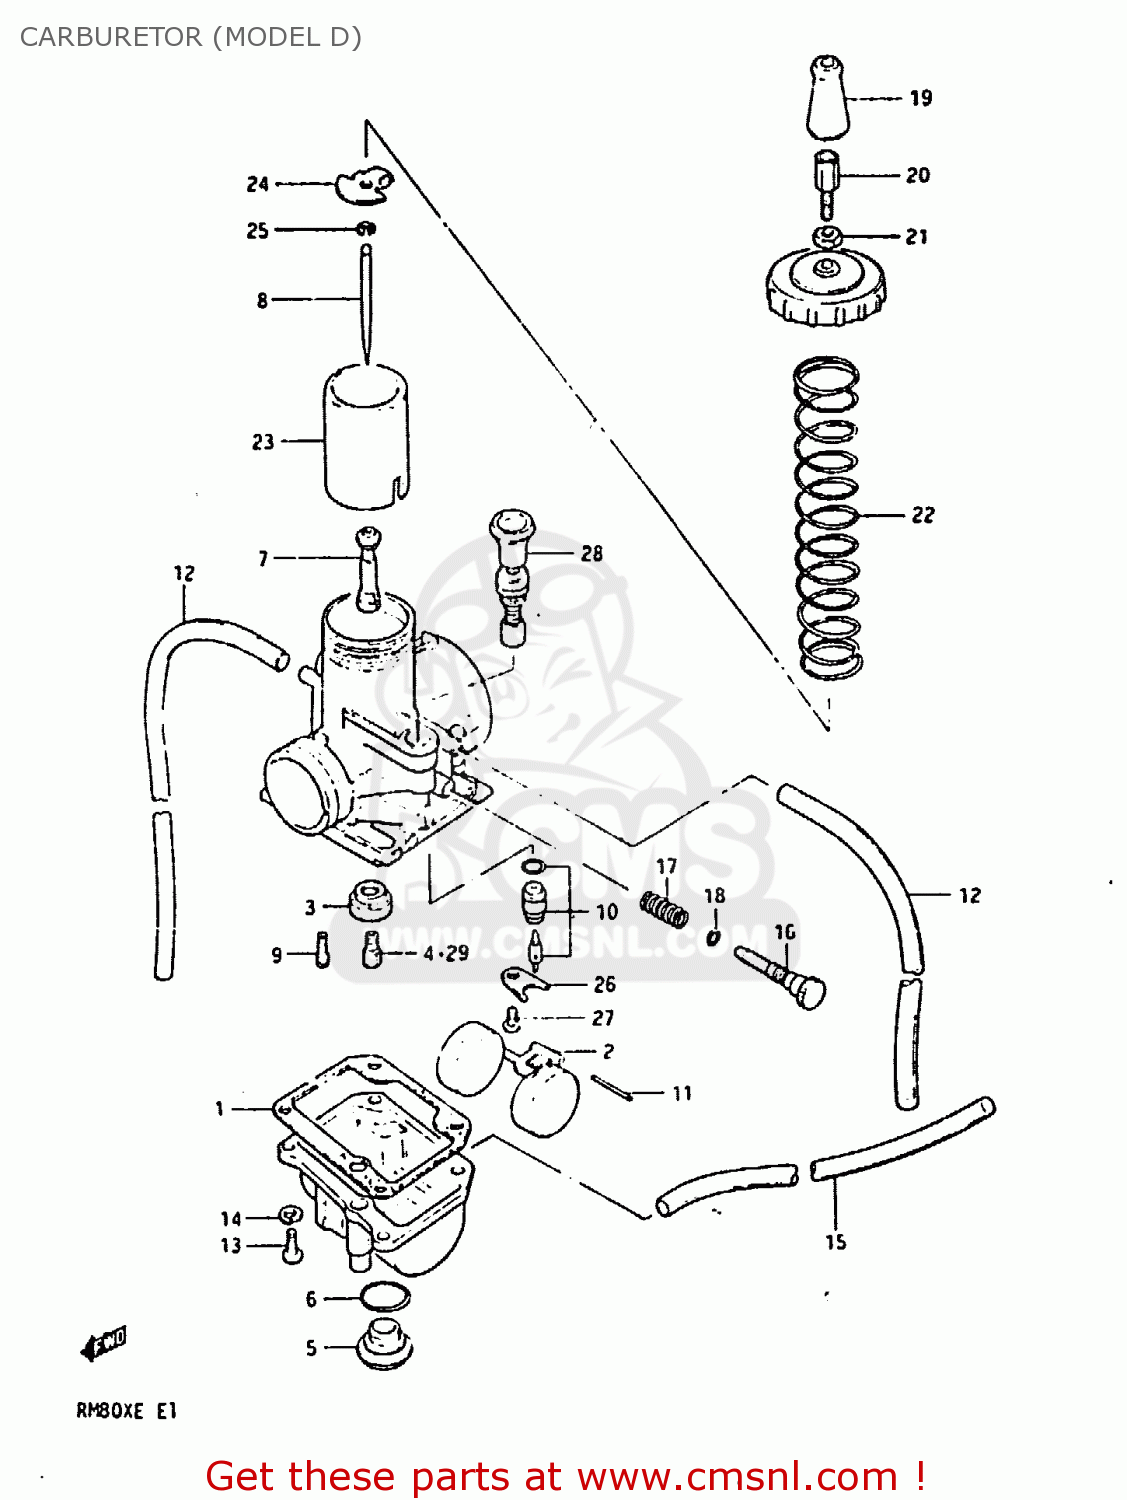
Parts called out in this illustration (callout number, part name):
1	GASKET,FLOAT CHAMBER (NAS)
2	FLOAT
3	RING
4	JET
5	PLUG
6	O RING
7	JET,NEEDLE
8	NEEDLE,JET
9	JET
10	VALVE ASSEMBLY,NEEDLE
11	PIN,FLOAT
12	HOSE
13	SCREW
14	LOCK WASHER
15	HOSE
16	ADJUSTER
17	SPRING
18	O RING
19	CAP,RUBBER
20	ADJUSTER,CABLE
21	NUT
22	SPRING,THROTTLE VALVE
23	VALVE,THROTTLE
24	PLATE,THROTTLE VALVE
25	CLIP
26	PLATE
27	SCREW
28	VALVE ASSEMBLY,STARTER
29	JET
